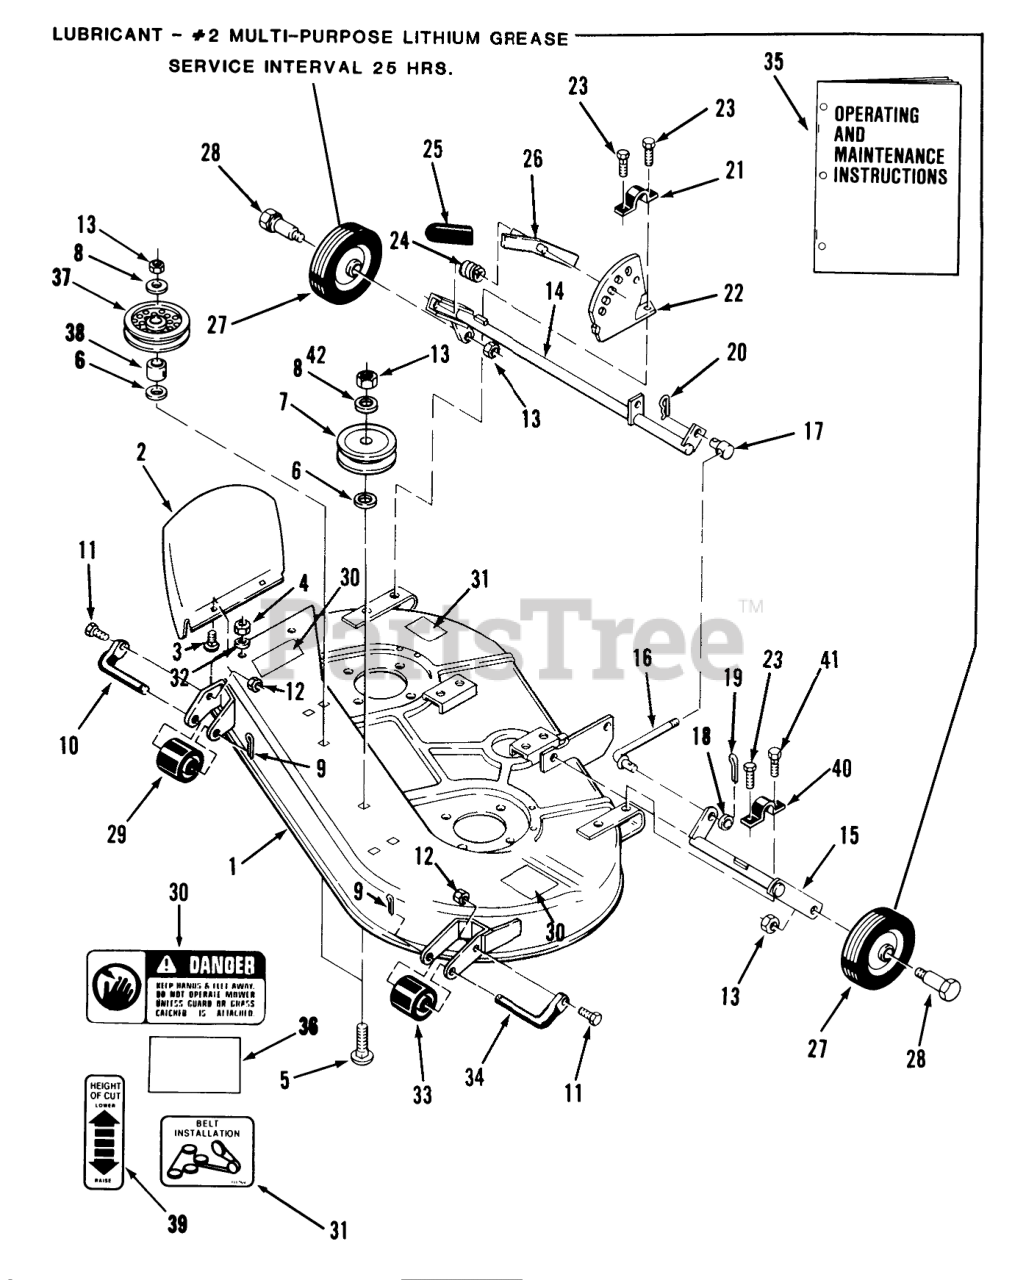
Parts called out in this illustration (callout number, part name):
1	Deck-Mower
2	Chute Extension
3	Bolt
4	Nut
5	Bolt
6	Washer
7	PULLEY-IDLER
8	WASHER
9	Cotter Pin
10	ROLLER-SHAFT
11	Bolt
12	Nut
13	NUT
14	Gage Wheel Support RH
15	WA GAG WHL R
16	ROD CONNECTING
17	TRUNNION
18	Washer
19	Pop Rivet
20	Hairpin
22	Quadrant
23	Bolt
24	SPRING-COMPRESSION
26	Lever
27	WHEEL
28	BOLT-SHOULDER
29	Roller
30	Danger Decal
31	DECAL BELT INSTALLAT
32	WASHER 5/16 SAE
33	ROLLER
34	SHAFT-ROLLER
35	Operator-s Manual 05-37SC02
35	Manual-Operators
36	DECAL-OVERLAY
37	PULLEY-FLAT IDLER B
38	SPACER
39	DECAL-HOC
40	CLAMP B
41	Bolt
42	Washer
